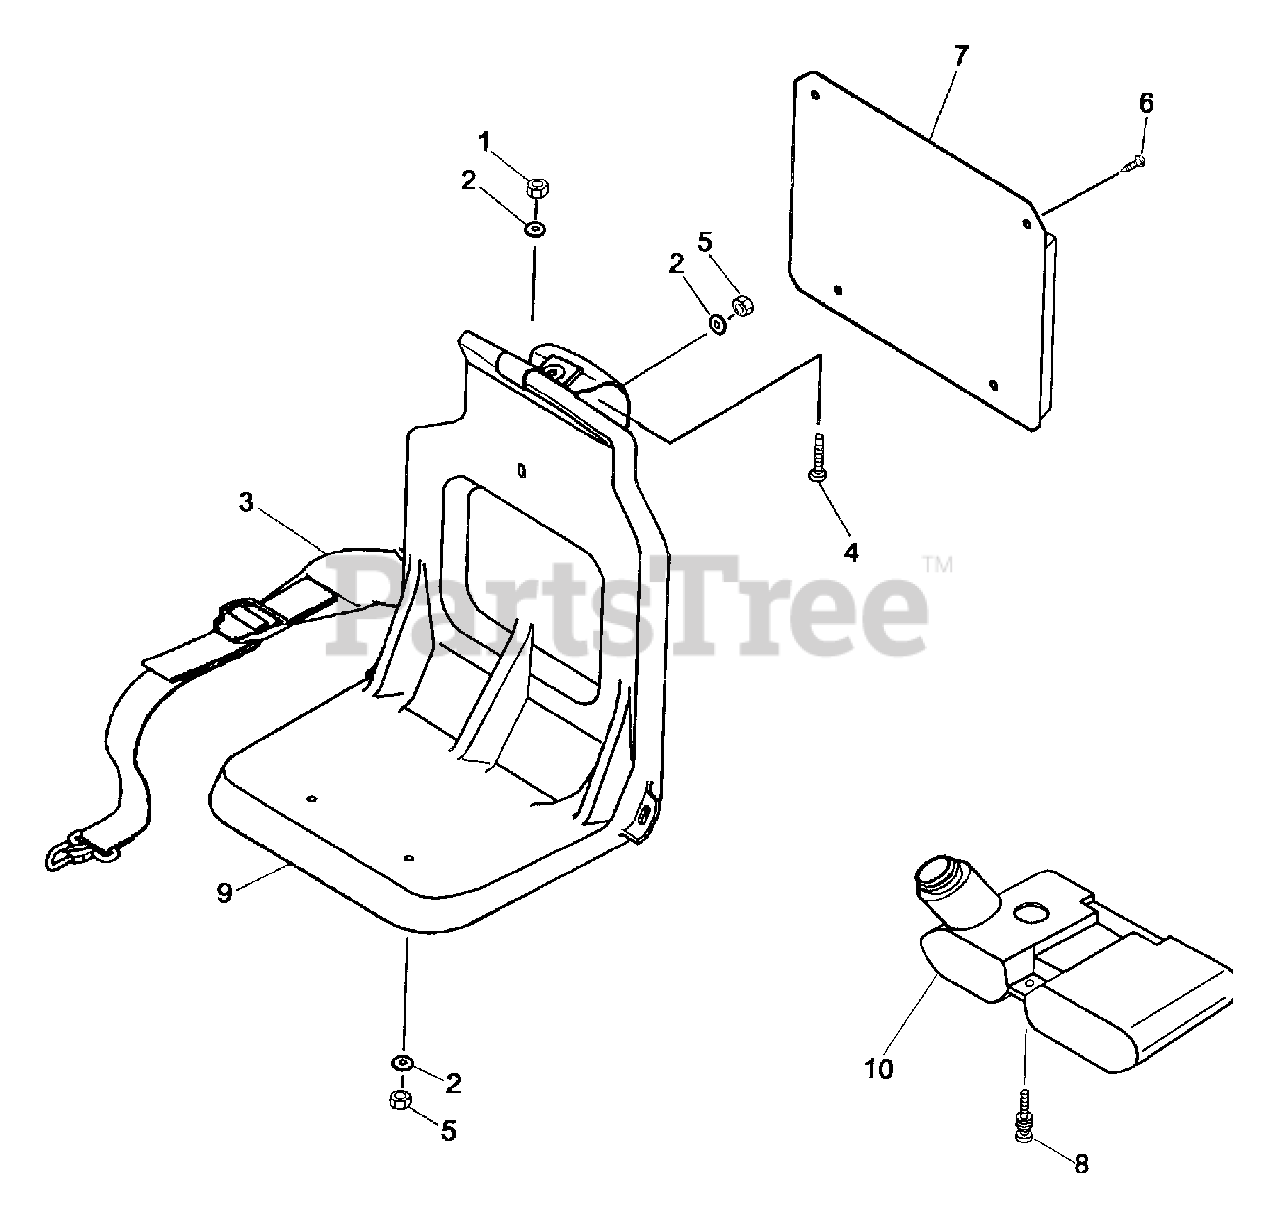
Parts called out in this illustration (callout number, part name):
1	FLANGE NYLON NUT
2	Washer, M6
3	SHOULDER BAND
4	TRUSS SCREW
5	NYLON NUT
6	CLIP
7	KNAPSACK PAD
8	SCREW M5X16
9	KNAPSACK FRAME
10	FUEL TANK
